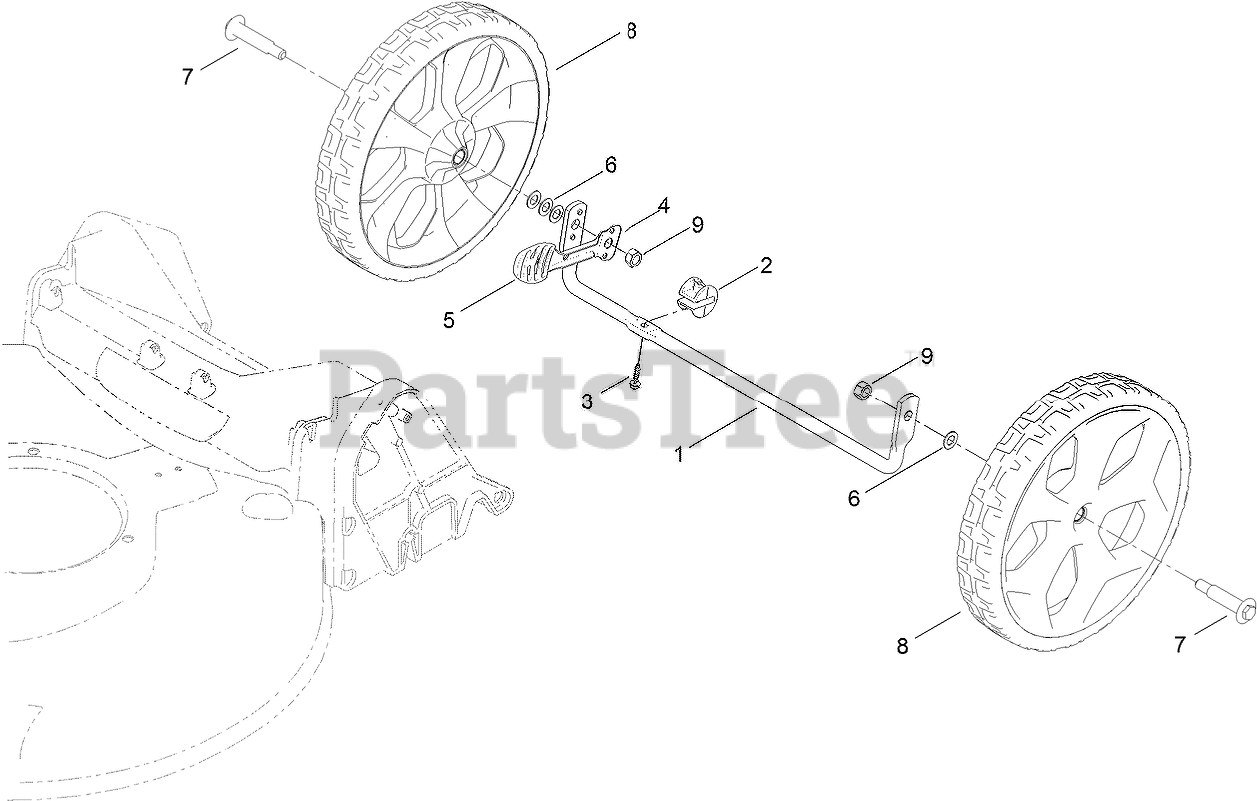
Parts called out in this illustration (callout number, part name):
1	AXLE-REAR
2	STOP-AXLE
3	SCREW-HWH
4	ARM-SPRING, REAR
5	KNOB-LEVER, HOC
6	WASHER
7	BOLT-SHOULDER
8	11 INCH WHEEL ASM
9	NUT-HEX
